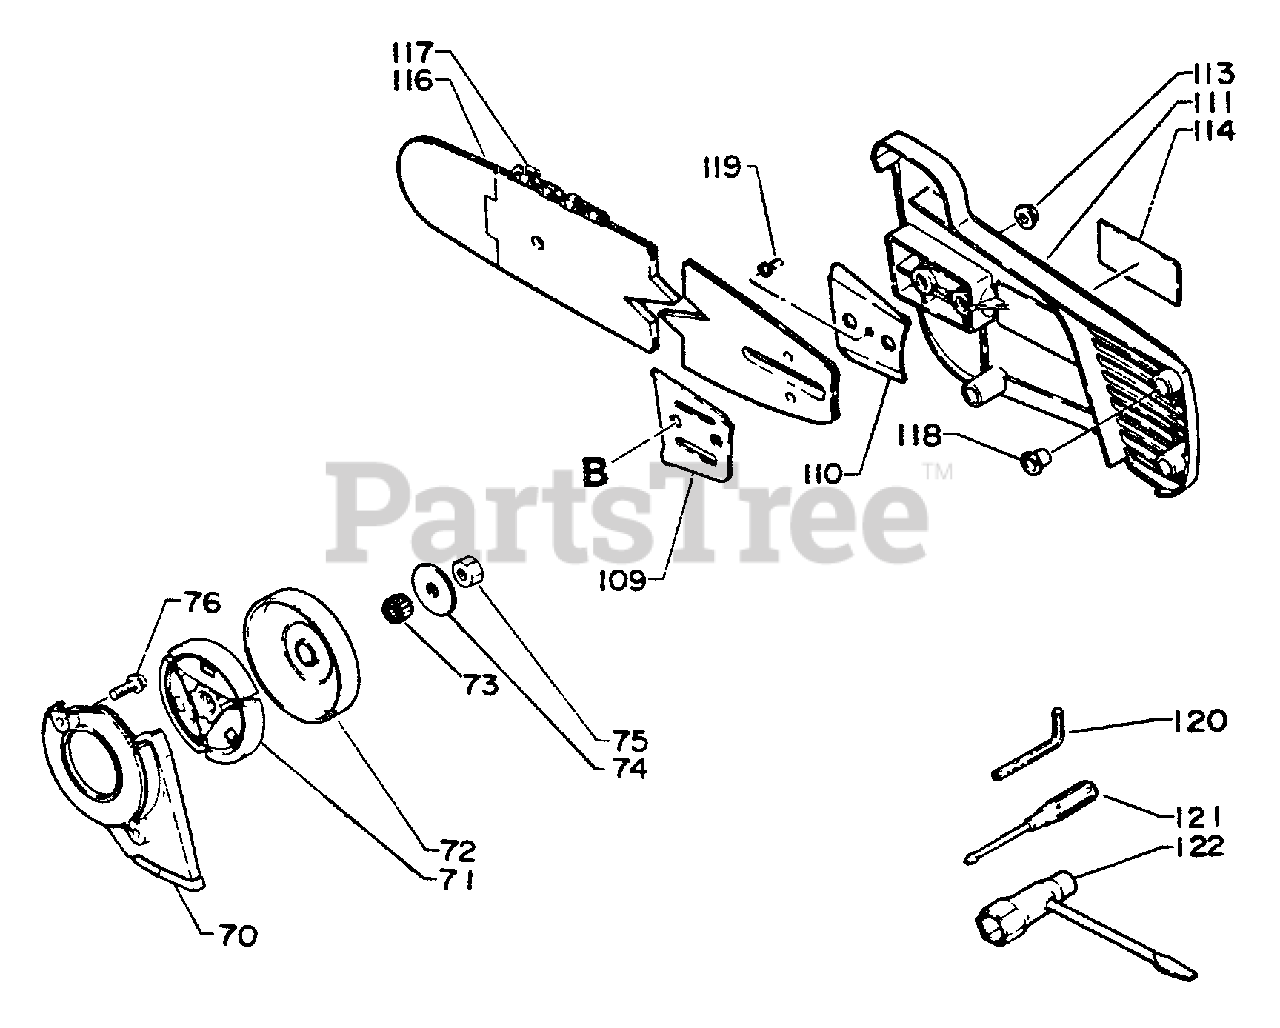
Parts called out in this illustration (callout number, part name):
70	PLATE
71	CLUTCH ASSY
72	DRUM, CLUTCH
73	BEARING, NEEDLE
74	WASHER, CLUTCH
75	LOCKNUT
76	SCREW 5×16
109	PLATE, GUIDE - INNER
110	PLATE, GUIDE - OUTER
111	GUARD, SPROCKET
113	NUT - 6 -- FLANGE
114	LABEL - ECHO
116	GUIDE BAR
118	PIN, DOWEL
119	SCREW 3×6
120	WRENCH, ALLEN 4 MM
121	SCREWDRIVER, PHILLIPS
122	T-WRENCH 10×19 MM
